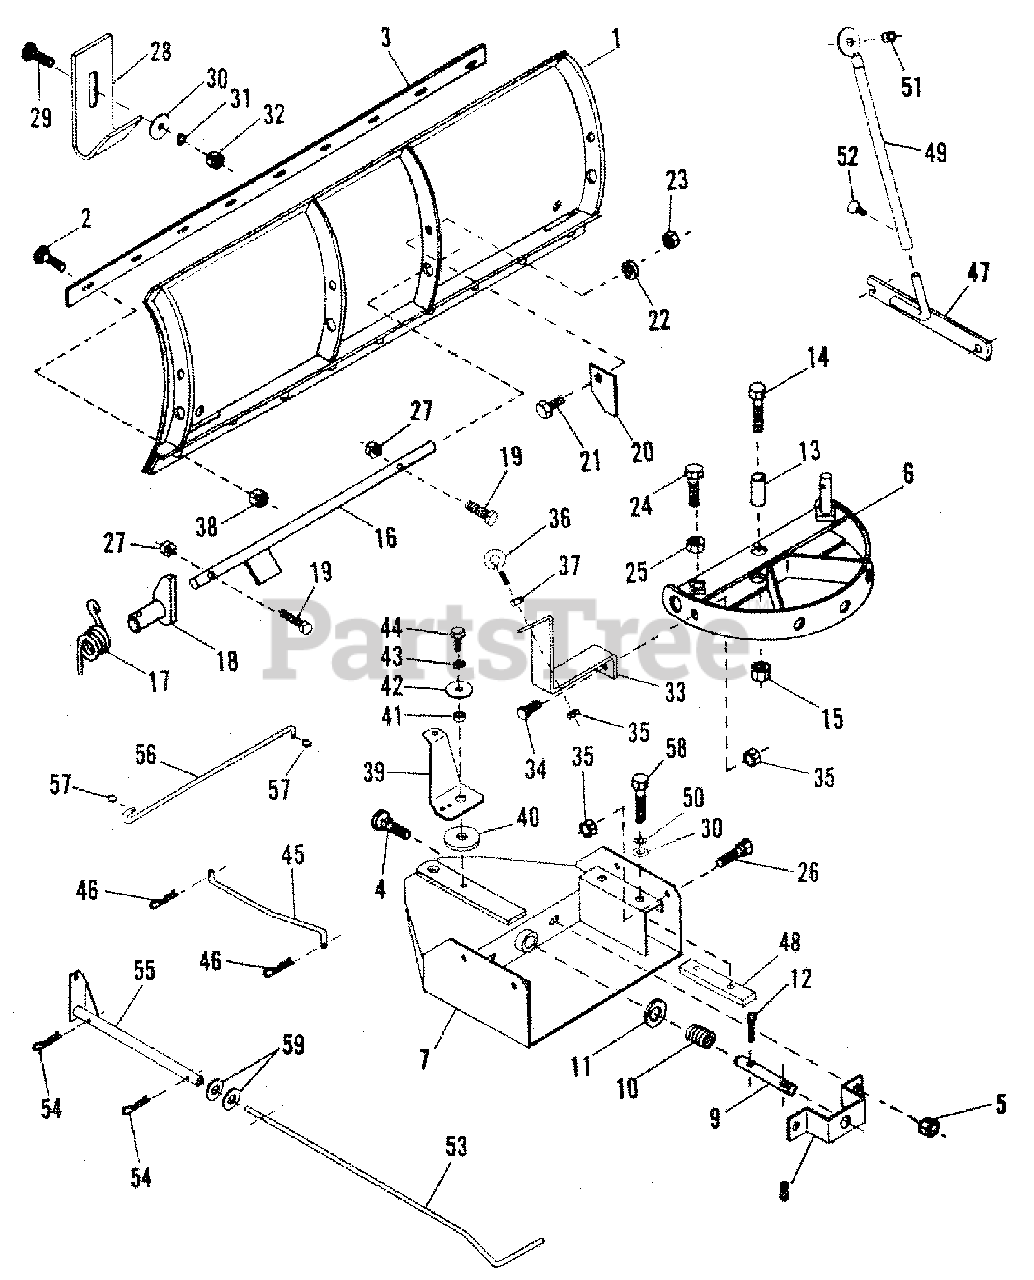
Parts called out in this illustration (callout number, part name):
1	Blade Assembly -54"
2	Bolt - 5/16-18 x 1" Carriage
3	Scraper Blade - 54"
4	Bolt - 5/16-18 x 3/4 Carriage
5	Nut - 5/16-18 Hex Lock
6	Pivot Quadrant Assembly
7	Pivot Bracket Assembly
8	Lock Pin Bracket
9	Lock Pin
10	Spring
11	Flat Washer - 21/32 x 1-5/16 x .095
12	Cotter Pin 1/8 x 1-1/4
14	Bolt - 1/2-13 x 3-1/2 Hex Head
15	Nut - 1/2-13 Hex Lock
16	Breakover Pin Assembly
17	Torsion Spring
18	Spring Anchor Assembly
19	Bolt - 1/4-20 x 1-1/2 Hex Head
20	Blade Stop Strap
21	Bolt - 5/8-11 x 1-1/4 Hex Head
22	Lock Washer - 5/8 Med
23	Nut - 5/8-11 Hex Jam
24	Bolt - 1/2-13 x 1-1/2 Hex Head
25	Nut - 1/2-13 Hex Jam
26	Bolt - 3/8-16 x 2-1/4 Hex Head
27	Nut - 1/4-20 Hex Lock
28	Skid Shoe
29	Bolt - 1/2-13 x 1" Carriage
30	Flat Washer- 17/32 x 1-1/16 x .095
31	Lock Washer - 1/2 Med
32	Nut - 1/2-13 Hex
33	Pivot Control Bracket
34	Bolt - 3/8-18 x 1-1/4 Hex Head
35	Nut - 3/8-16 Hex Lock
36	Eye Bolt
37	Nut -3/8-16 Hex
38	Nut - 5/16-18 Hex Serrated Flange
39	Pivot Release Bracket
40	Flat Washer - 17/32 x 2" x .134
41	Spacer
42	Flat Washer - 13/32 x 1-1/2 x .065
43	Lock Washer - 3/8 Med
44	Bolt - 3/8-16 x 3/4 Hex Head
45	Lock Pin Release Rod
46	Hitch Pin
47	Control Rod Support Anchor Assembly
48	Tapped Strap
49	Control Rod Support Assembly
50	Lock Washer - 1/2" Internal Tooth
51	Control Rod Guide Bushing
52	Thumb Screw
53	Control Rod
54	Hitch Pin
55	Pivot Control Arm Assembly
56	Pivot Release Rod
57	Spring Clip
58	Bolt - 12-13 x 2-1/4 Hex Head
59	Flat Washer - 19/32 x 1-3/16 x .095
